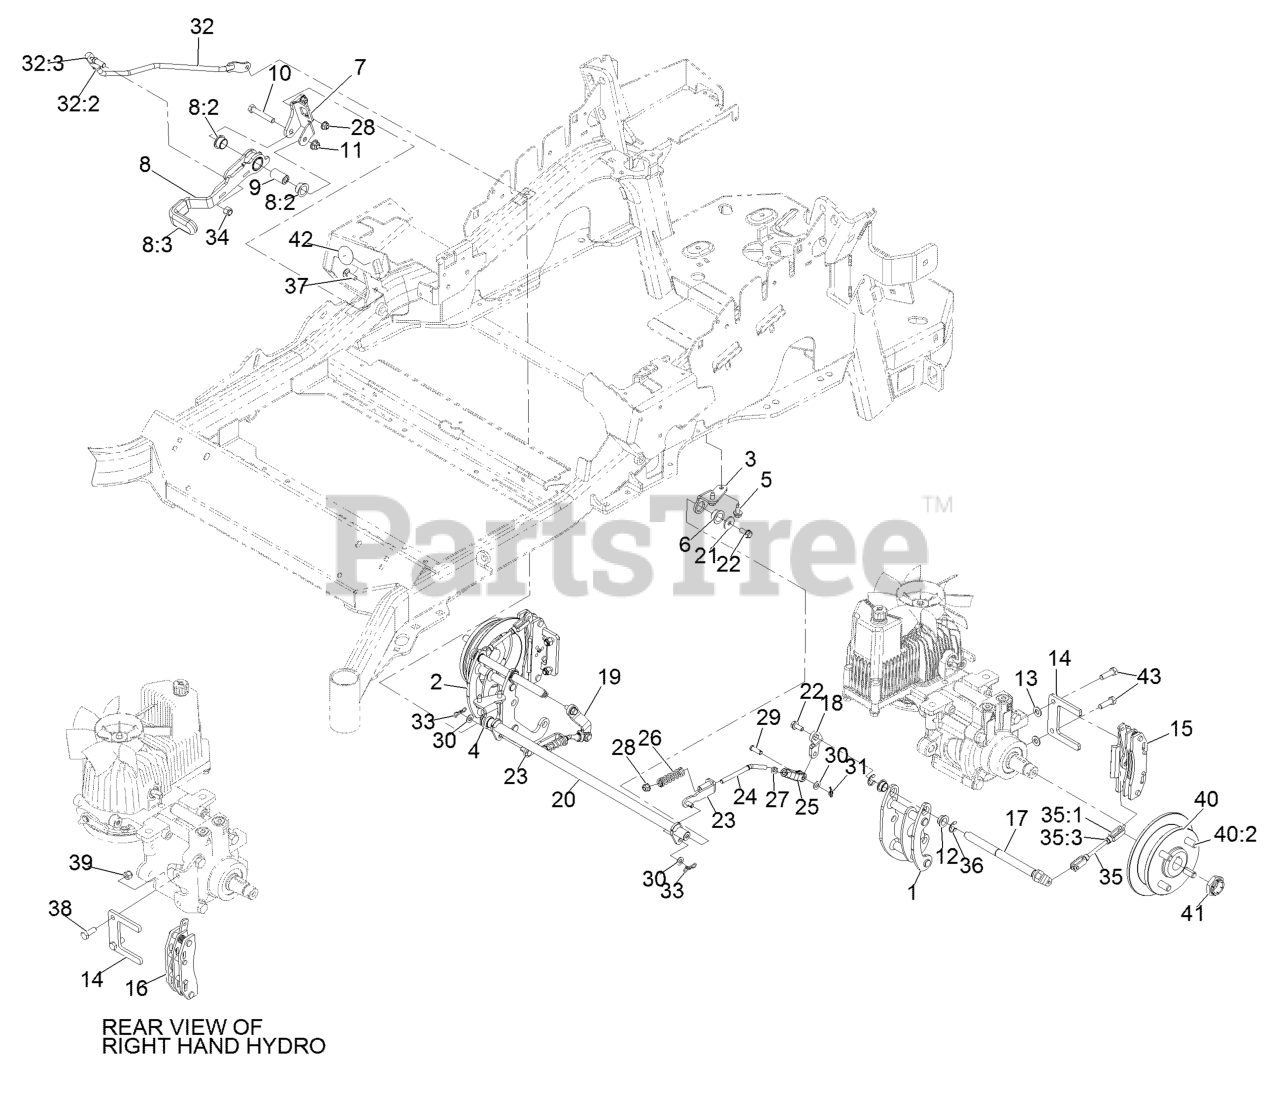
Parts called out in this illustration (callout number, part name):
3	MOUNT-PIVOT, LH
4	MOUNT-PIVOT, RH
5	Screw-HWH 5/16-18 X 3/4 Tf
6	BUSHING-FLANGE
7	BRACKET-MOUNT
8	BRAKE LEVER ASM
8:2	BUSHING-FLANGE
8:3	GRIP-LEVER
9	HANDLE-PIVOT, BRAKE
10	SCREW-HH
11	NUT-HF, NI
12	BUSHING
13	WASHER-FLAT
14	PLATE-MOUNT, BRAKE
15	CALIPER-BRAKE
16	CALIPER-BRAKE, RH
18	ARM-INNER, LH
19	ARM-INNER, RH
20	SHAFT-CROSS
21	WASHER-FLAT
22	SCREW-HHF
23	BRACKET-L
24	LINKAGE-MID
25	YOKE-OFFSET
26	SPRING-COMPRESSION
27	NUT-JAM
28	NUT-HF, NI
29	PIN-CLEVIS
30	WASHER-PLAIN
31	PIN-COTTER, LOCKING
32	FRONT LINKAGE ASM
32:2	END-TIE ROD, RH
32:3	NUT-HJ
33	PIN-COTTER, LOCKING
34	NUT-LOCK
35	REAR LINKAGE ASM
35:3	NUT-JAM
37	BOLT-CARR
38	SCREW-HH
39	NUT-LOCK, NI
40	WHEEL HUB ASM
40:2	STUD-WHEEL
41	LOCKNUT
42	DECAL-COVER
43	SCREW-LOCK, PATCH
